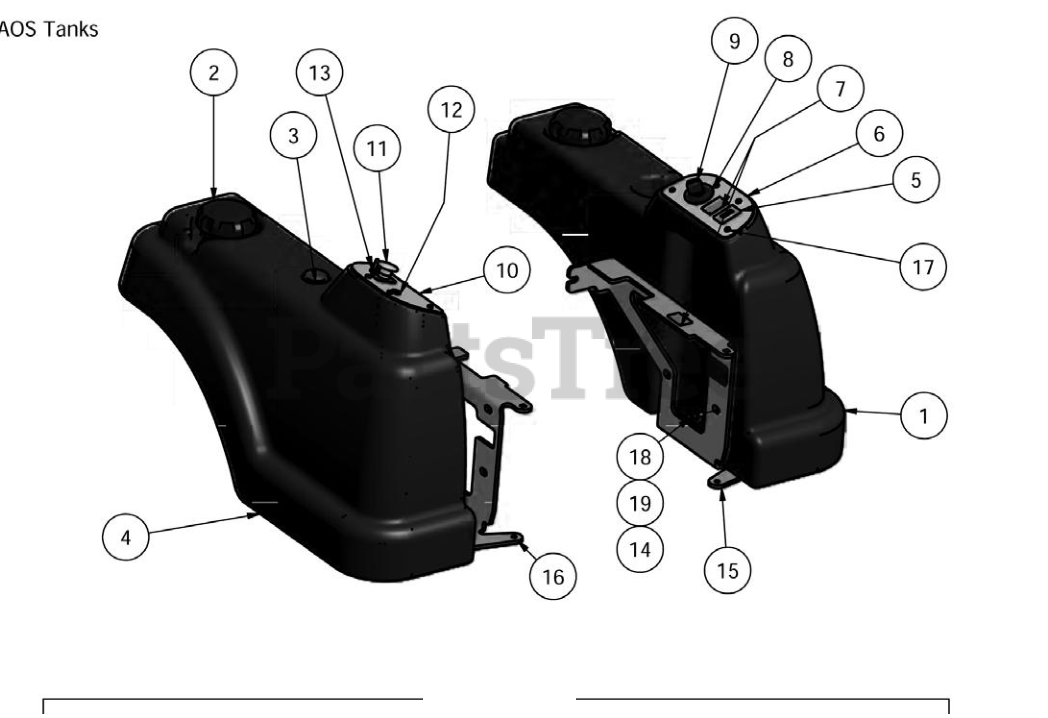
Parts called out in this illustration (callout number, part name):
1	Right Fuel Tank
3	Fuel Gauge and Grommet
4	Left Fuel Tank
5	Tachometer
6	Control Panel (Left)
7	control panel stop
8	Ignition Switch
9	Ignition Key
10	AOS control panel (Right)
11	PTO Engager
13	Deck Lift Joystick
14	.505 Nylon Spacer
15	Tank Support-Left
16	Tank Support-Right
17	10-32 x 3/8" Button Socket Head Bolt
18	5/16" x 1" Hex Bolt
19	5/16" Lock Washer
